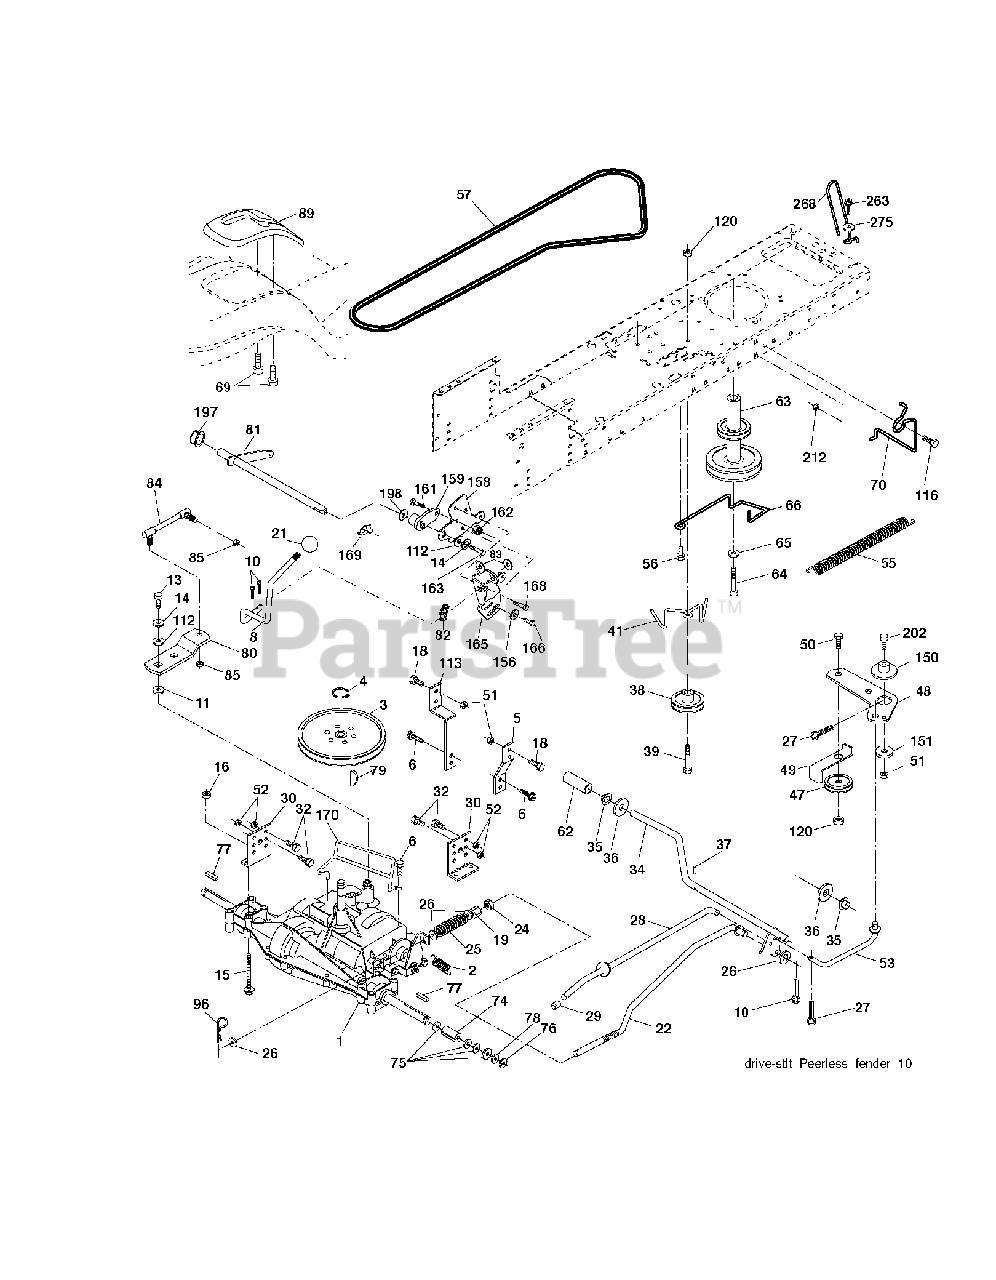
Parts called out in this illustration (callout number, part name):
2	SPRING,BRAKE RETURN
3	PULLEY TRANS
4	RETAINING RING LT
5	STRAP TORQUE
6	SCREW 5/16"
8	ROD SHIFT FENDER ADJUST LT
10	PIN COTTER
11	WASH-SHFT PLT LT
13	BOLT 1/4-28X3/4
14	LOCKWASHER
15	BOLT HEX 5/16-18 GR 5
16	NUT.71038.31-18.HEX.NYLOCK
19	NUT
21	KNOB T (1/2-HOLE)
22	ROD BRAKE
24	NUT
25	SPRING ROD LT
27	COTTER PIN
28	ROD, PARKING BRAKE
29	PLUNGER CAP
30	BRKT, MOUNT TRNSAXLE
32	BOLT
34	SHAFT, FOOT PEDAL
35	BEARING.NYLON
36	WASHER LT
37	DRIVE PIN
38	PULLEY IDLER COMPOSITE
41	KEEPER, BELT IDLER
47	IDLER PULLEY
48	BELLCRANK, CLUTCH
49	RETAIN BELT
50	BOLT.3/8-16X1.50
51	LOCKNUT
52	LOCKNUT
53	LINK.CLUTCH.7.66.2005
55	SPRING, RETURN LT
56	SCREW.3/8-16
57	BELT, V GROUND DRIVE 95 25
62	PEDAL COVER T
63	ENGINE PULLEY
64	BOLT HEX 7/16-20X4-1/4"
65	LOCKWASHER
66	KEEPER BELT ENGINE
69	SCREW.HI-LO.CONSOLE
70	KEEPER BELT ENG
74	SPACER AXLE
76	E-RING LT
77	SQUARE KEY
80	ARM SHIFT
82	SHIFT SPRING
83	WASHER
85	NUT LOCK CENTER 1/4 -28 FNTHD
89	CONSOLE SHIFT STLT
96	RETAINER M
112	WASHER LT
113	STRAP TORQUE LH LT
116	BOLT D
120	NUT LOCK FLG 3/8-16 UNC
150	SPACER, RETAINER
151	WASHER 12/32X2X10GA
156	WASHER.SRRTD.5/16
158	BRACKET
159	HUB.SHIFT
161	BOLT
162	NUT.CROWNLOCK.1/4
165	RP BRACKET
168	BOLT.SHOULDER.5/16-18X
169	PLATE.FASTENING.CROSS.SHAFT
170	KEEPER BELT T/A
197	NYLINER SNAP 5/8" ID
198	WASHER.NYL.7/8IDX.105"HYD CR
202	BOLT
212	NUT
263	SCREW, 3/8-16X3/4
275	WASHER
